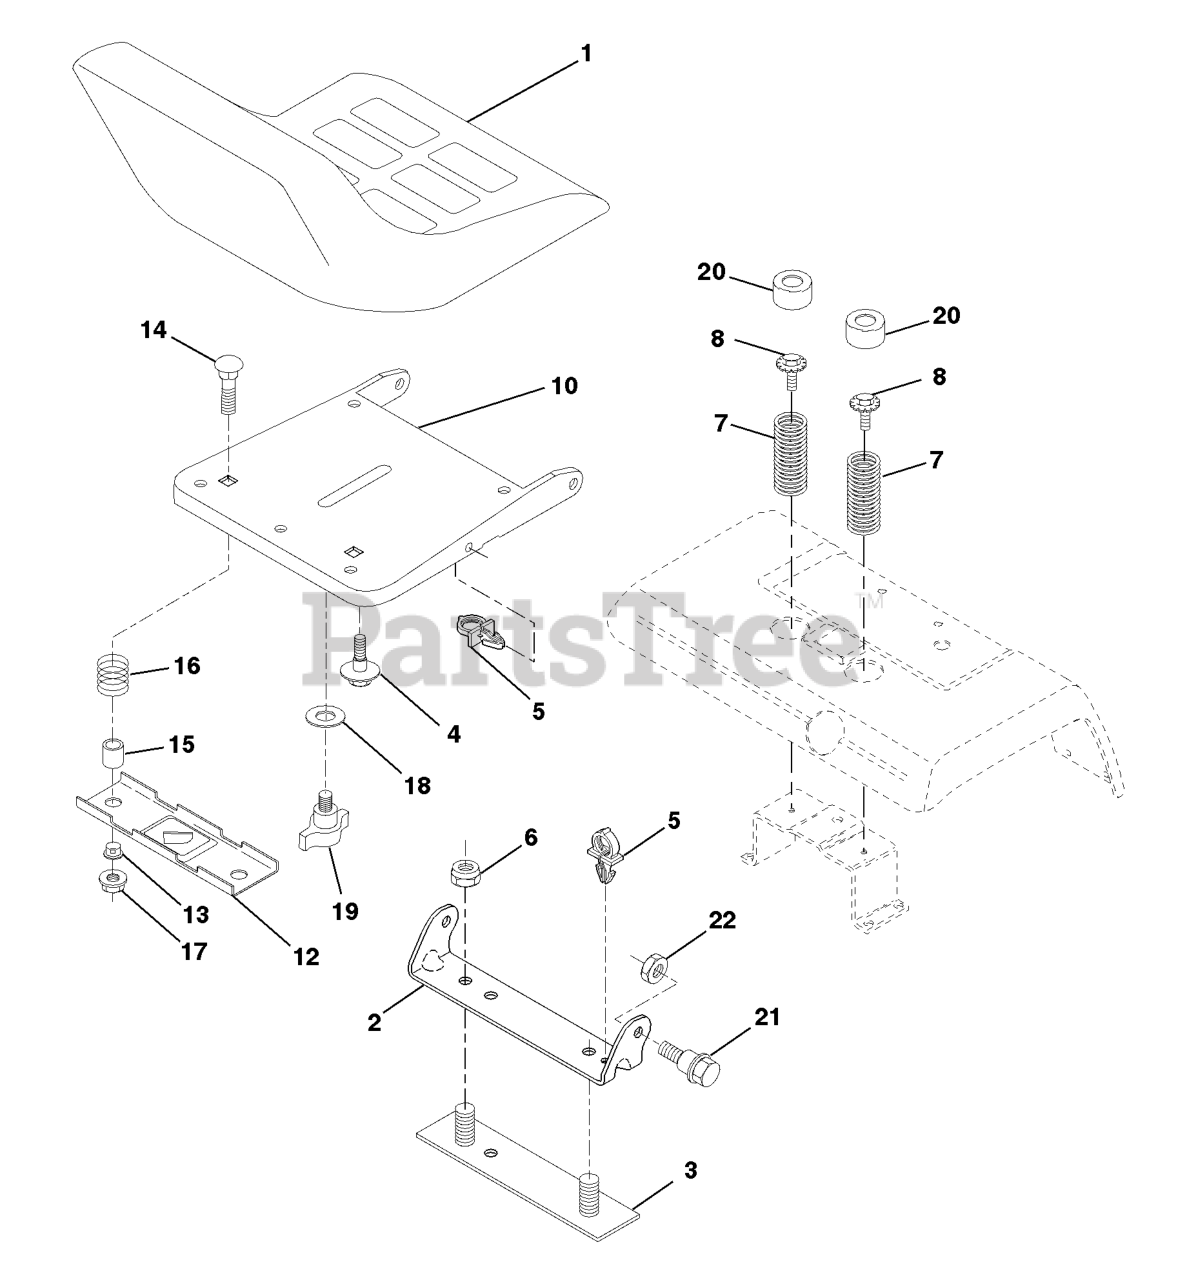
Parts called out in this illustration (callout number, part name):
1	SEAT
2	SEAT PIVOT BRKT
3	STRAP
4	BOLT,SHOULD
6	NUT
7	SPRING COMPRESSION
8	BOLT HEX WASHER HD 5/16-18
10	PAN, SEAT
12	BRKT SWITCH
14	BOLT.ROUND.HEAD.SQUARE.NECK
15	SPACER SPLIT
16	SPRING COMPRESSED
17	NUT T
19	KNOB.SEAT.ADJ.WINGNUT
20	CAP SPRING
21	BOLT SHOULDER 5/16-18
22	LOCKNUT
